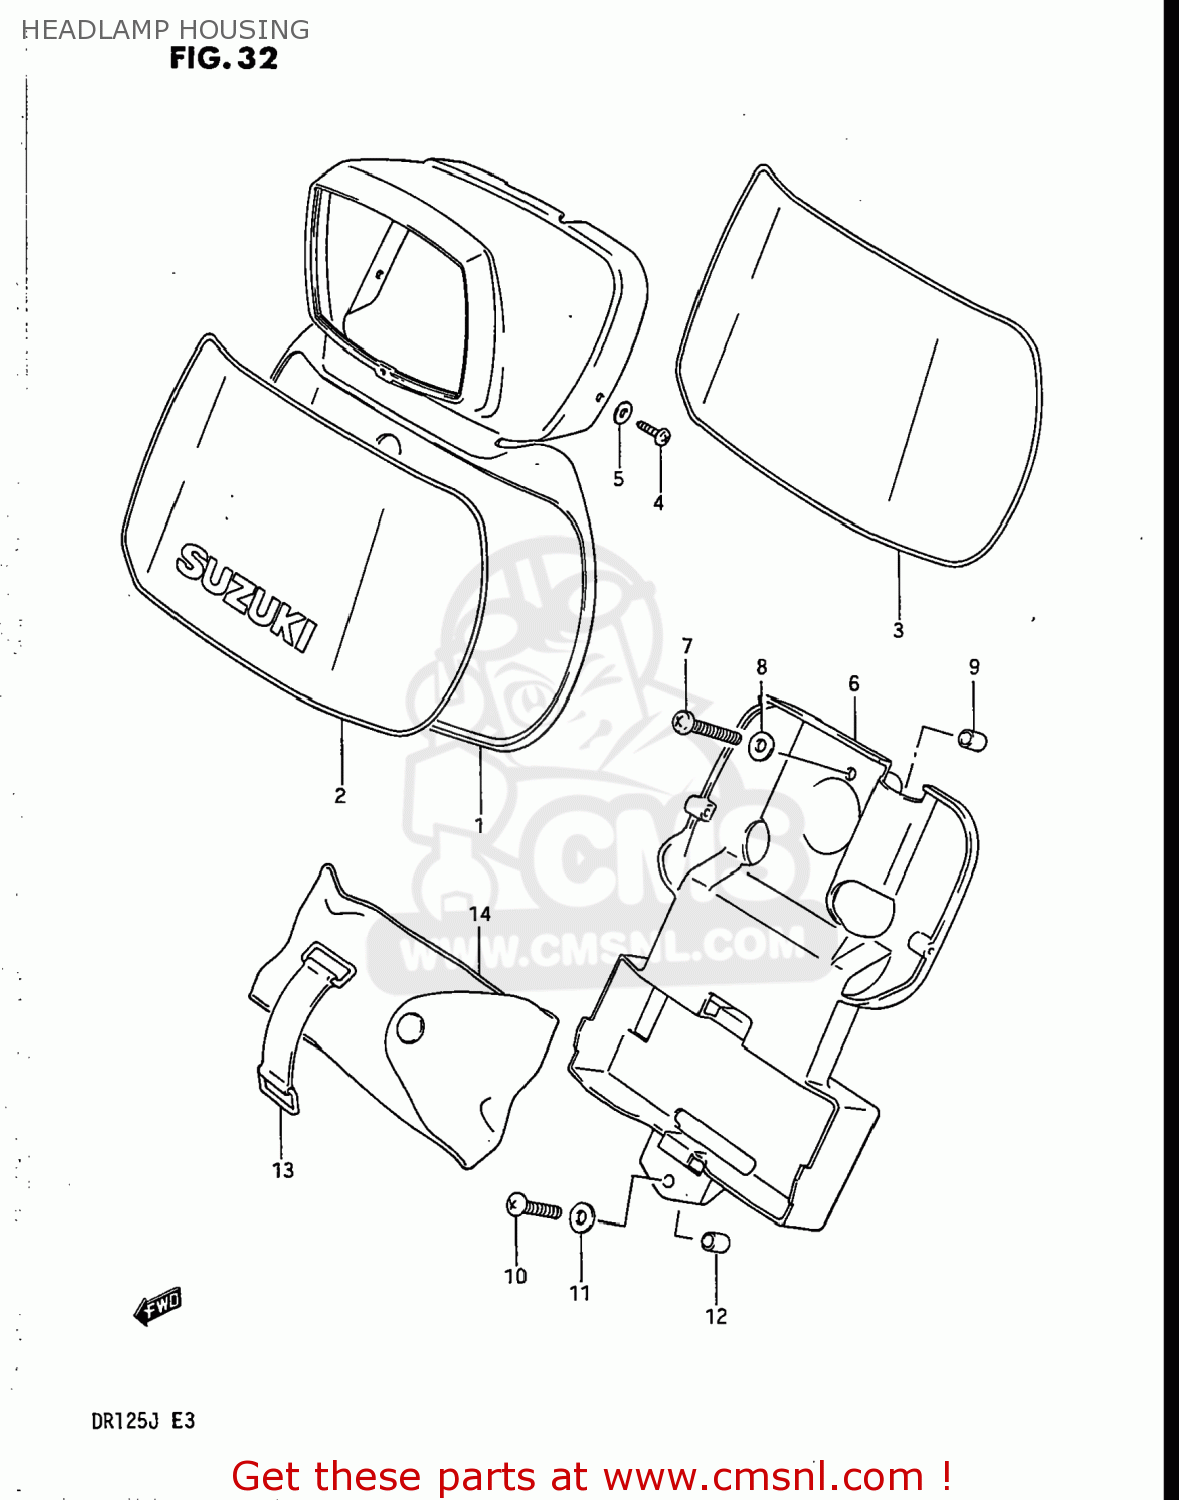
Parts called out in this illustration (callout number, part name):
1	HOUSING,HEADLAMP
2	TAPE SET,HEADLAMP COVER
3	TAPE SET,HEADLAMP COVER
4	TAPPING SCREW
5	WASHER 4MM
6	HOLDER,TOOL
7	SCREW
8	WASHER
9	SPACER (6.8X10X27.4)
10	SCREW
11	WASHER
12	SPACER (6.8X10X10)
13	BAND
14	TOOL SET
